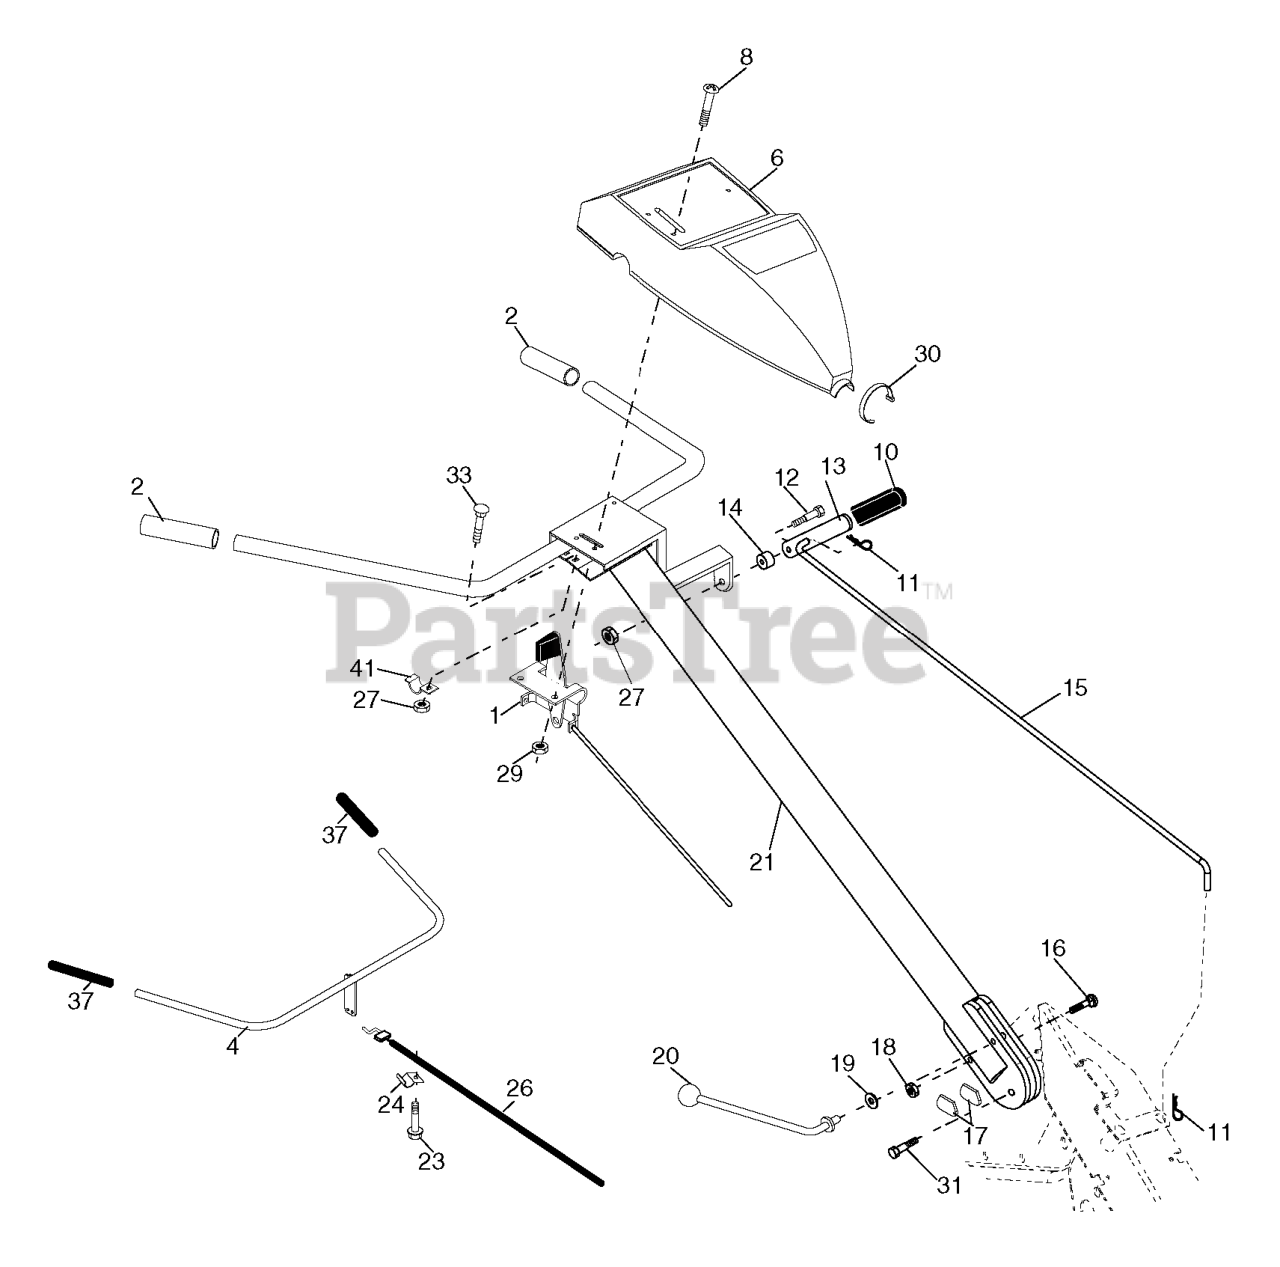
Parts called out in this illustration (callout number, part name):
1	THROTTLE.CONTROL.CRT.TILLER
2	KIT.GRIP.HANDLE.5.00.BLK.VINYL
4	CONTROL BAR ASSY
6	RP CONTROL PANEL
8	SCREW.PNHD.10-24
10	GRIP T
11	RETAINER M
12	SHOULDER BOLT ST
13	HANDLE.SHIFT.TILLER
14	GROMMET.RUBBER.CRT.TILLER
15	SHIFT ROD CRT
16	BOLT D
17	LOCK.HANDLE.CRT
19	WASHER CRT
20	LEVER.LOCK.CRT
21	REPL BY 532 1805-17
23	TAPPING SCREW
24	CONDUIT.CLIP.PLATED
26	CABLE.CLUTCH
27	NUT T
29	NUT **
30	TIE CABLE CRT
31	BOLT.PIVOT
33	BOLT
37	GRIP BAR CRT(1)
41	CLAMP.BAR.CRT.BLACK
